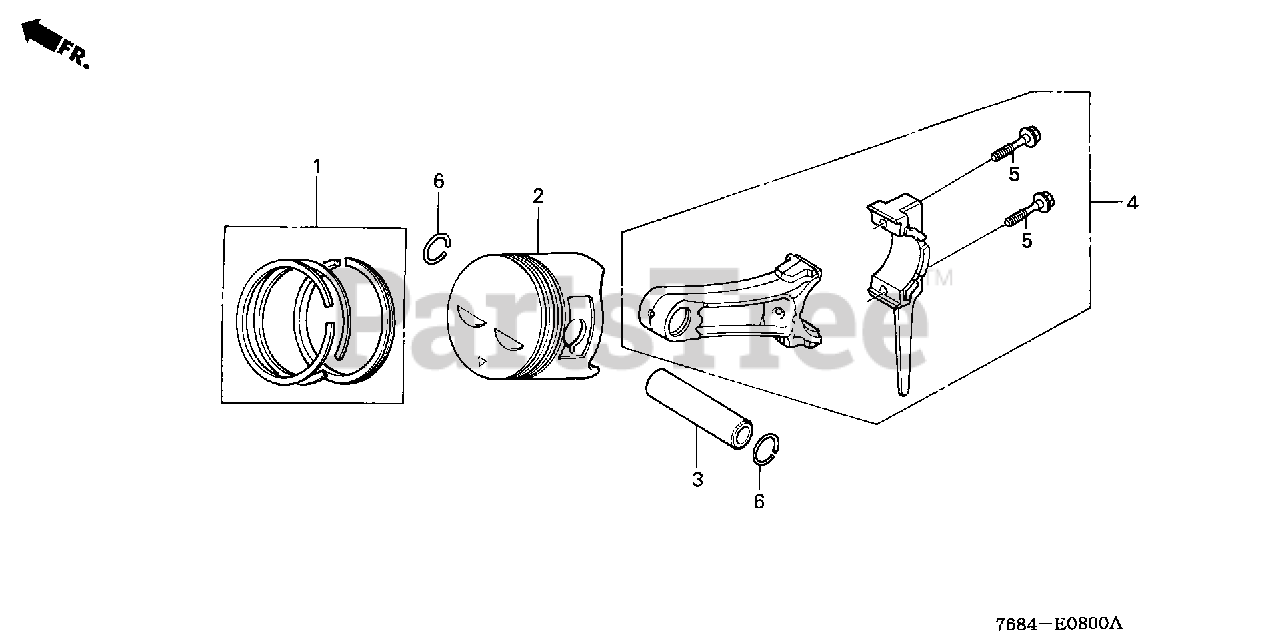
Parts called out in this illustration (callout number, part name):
1	RING SET, PISTON (STD) (NIPPON)
1	RING SET, PISTON (STD) (TEIKOKU)
1	RING SET, PISTON (0.25) (TEIKOKU)
1	RING SET, PISTON (0.50) (TEIKOKU)
1	RING SET, PISTON (0.75) (NIPPON)
2	PISTON (STD)
2	PISTON (0.25)
2	PISTON (0.50)
2	PISTON (0.75) (NOT AVAILABLE)
3	PIN, PISTON
4	ROD ASSY., CONNECTING (STD)
4	ROD ASSY., CONNECTING (0.25 LOWER SIZE)
5	BOLT, CONNECTING ROD
6	CLIP, PISTON PIN (18MM)
